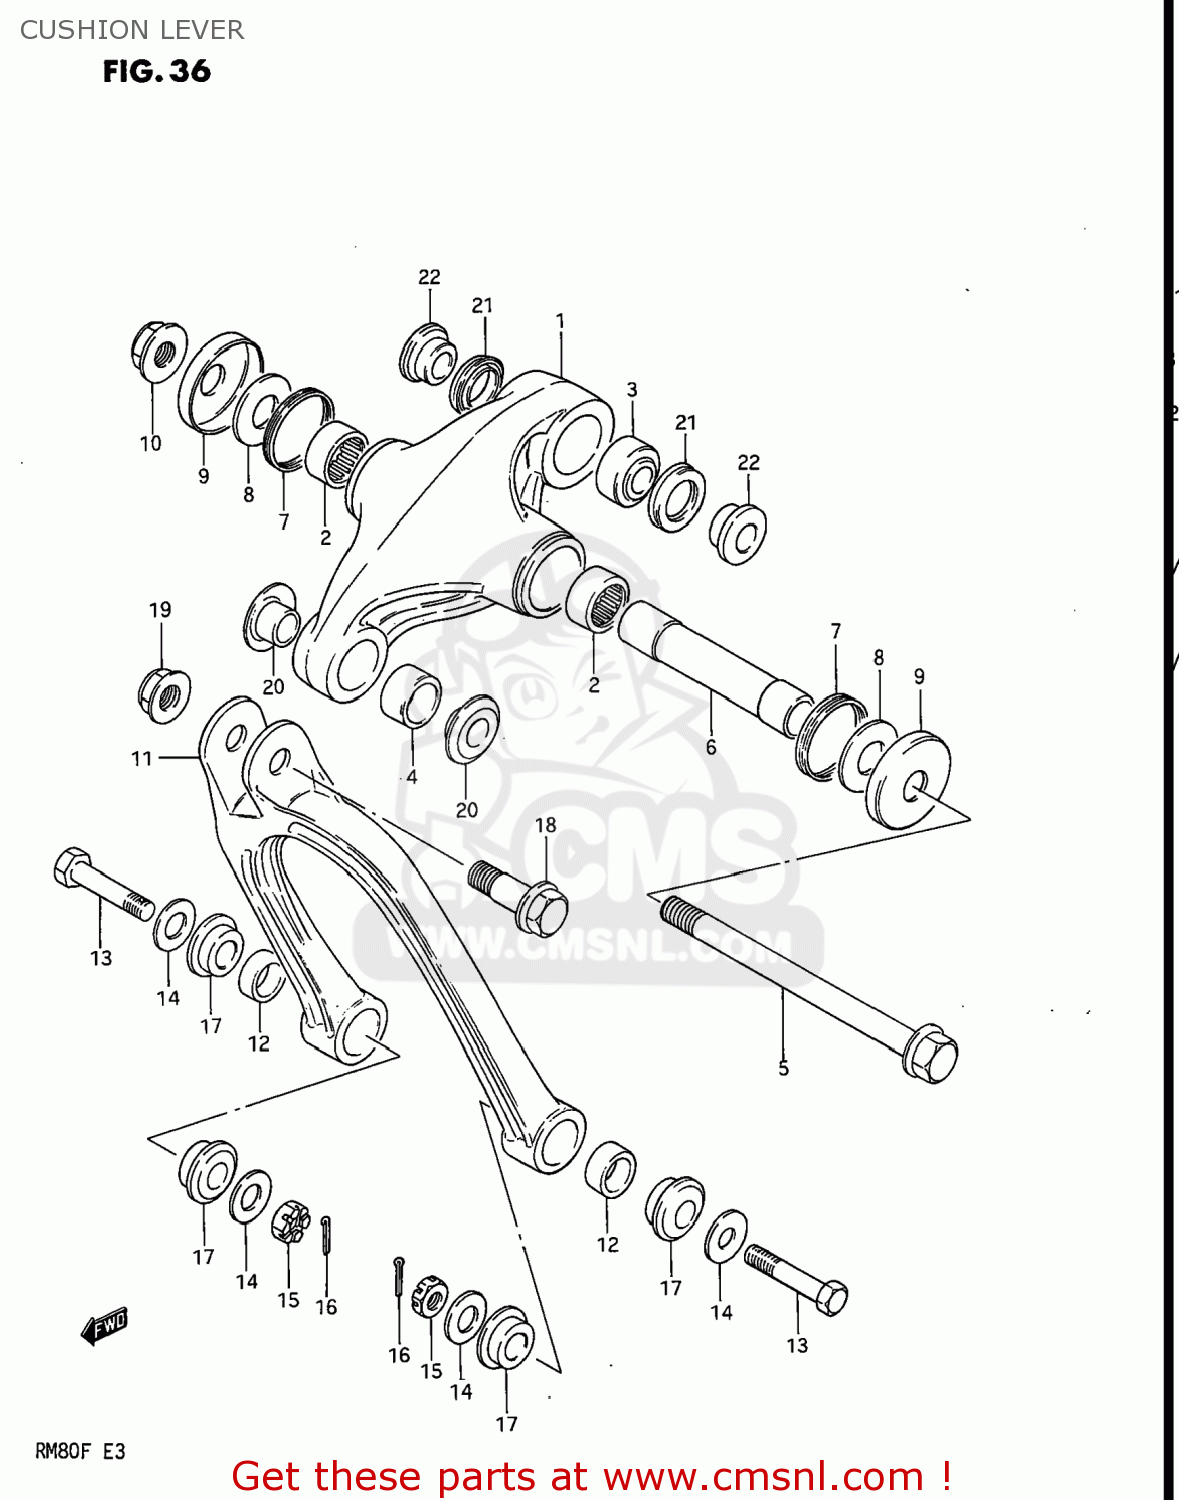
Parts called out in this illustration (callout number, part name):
1	LEVER SET,REAR CUSHION
2	BEARING(17X25X20)
3	BEARING
4	BUSH,FR
5	SHAFT,REAR CUSHION LEVER
6	SPACER,REAR CUSHION LEVER
7	DUST SEAL,RR CUSHION LEVER
8	WASHER
9	DUST COVER,REAR CUSHION
10	NUT 12MM
11	ROD SET,REAR CUSHION LEVER
12	BUSHING
13	BOLT,REAR CUSHION LEVER
14	WASHER
15	NUT 8MM
16	PIN 20X20
17	SPACER,REAR CUSHION ROD
18	BOLT(10X44)
19	NUT
20	SPACER,REAR CUSHION,FRONT
21	DUST SEAL,REAR CUSHION,LEFT
22	SPACER
